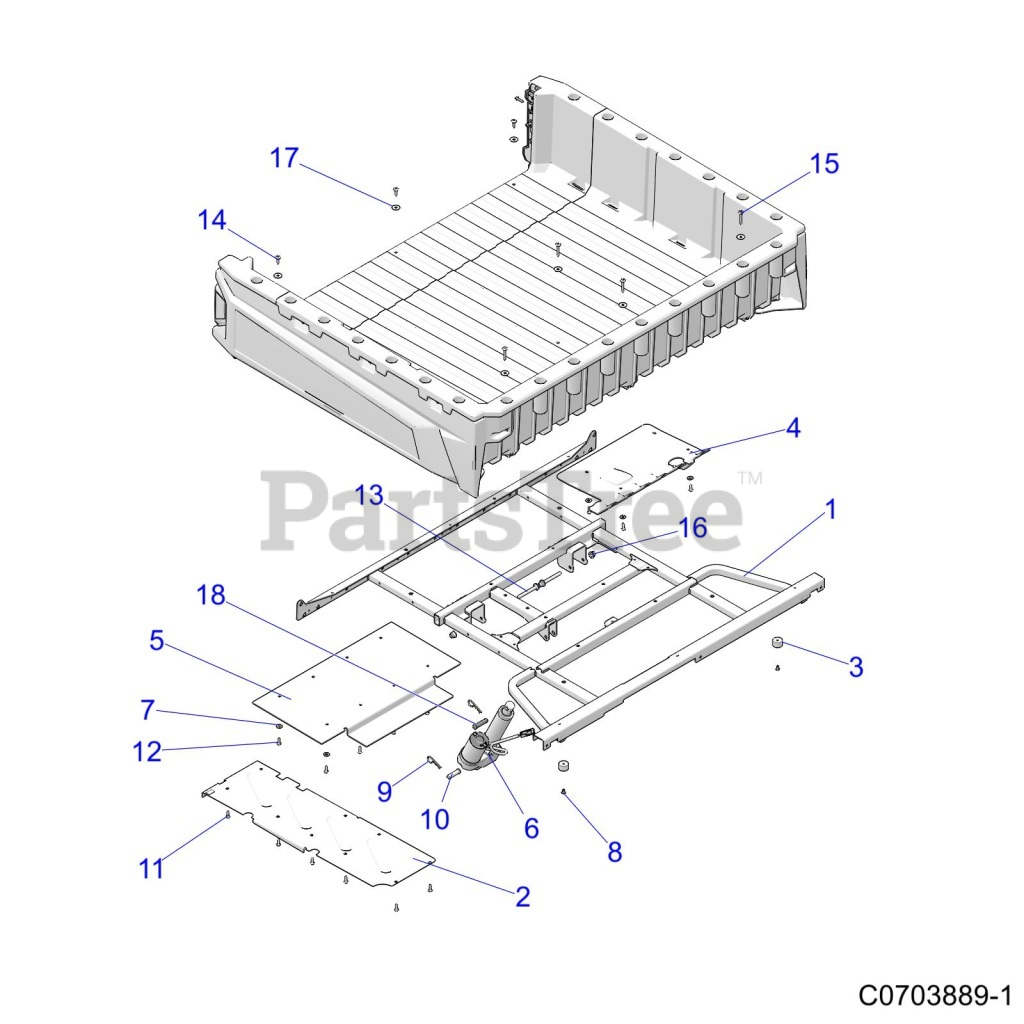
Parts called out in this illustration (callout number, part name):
1	WELD-FRAME,BOX,BLK
2	SHIELD-BOX,CARGO
3	BUMPER-BOX
4	SHIELD-HEAT,FOIL,BOX,RGR
5	SHIELD-HEAT,EXHAUST,REAR
6	ACTUATOR,BOX LIFT,CMPT,TTN
7	WASHER-.312 X .734 X .065-Z
8	RIVET(50)
9	CLIP, HITCH PIN
10	PIN, CLEVIS
11	SCR-TXPH-#14 X .75 HI-LO RIE
12	SCR-TXPH-#14X3/4 HI/LO CLR
13	SCR-HXFL-M10X1.25X80 8.8 ZOD
14	SCR-TXTH-M6X1.0X25 RIE
15	SCR-TXTH-M6X1.0X45 RIE
16	NUT-M10X1.25,FLG,NYLOC-OLIVE D
17	WASHER-.281X1.00X.051
18	PIN, CLEVIS BOX LIFT 2"
